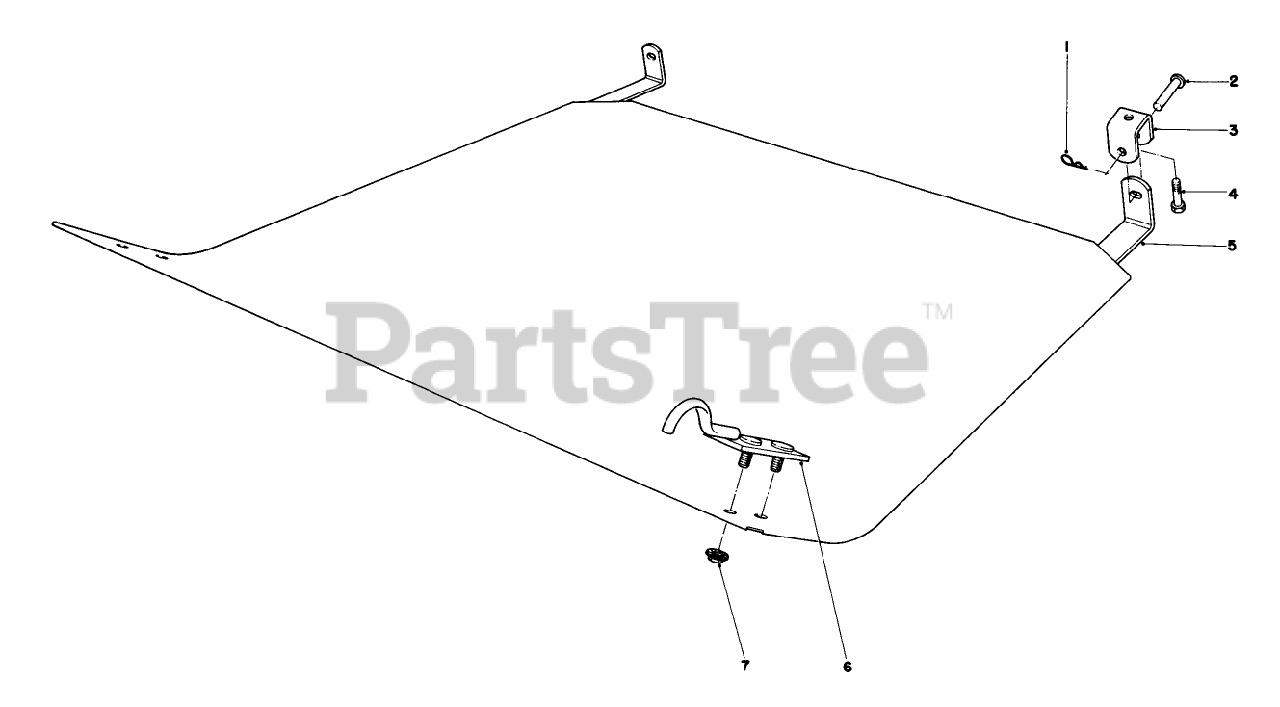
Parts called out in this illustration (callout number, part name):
1	PIN-HAIR
2	CLEVIS
3	Hanger-Belly Shield
4	SCREW-HH
5	Belly Shield
6	Belly Shield Hook
7	NUT-HF
